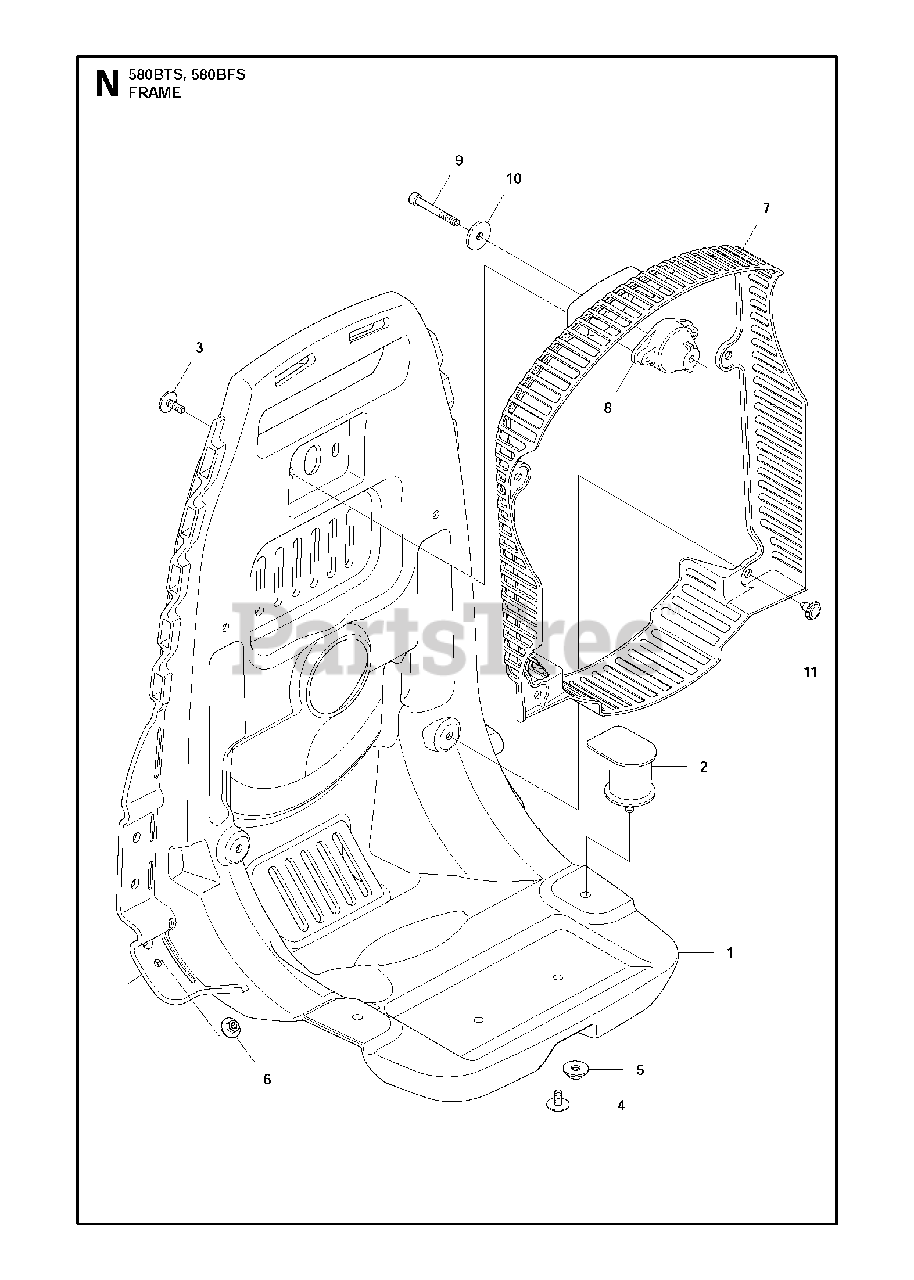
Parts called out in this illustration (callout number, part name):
7	NET ASSY
8	DAMPER UPPER
9	BOLT
